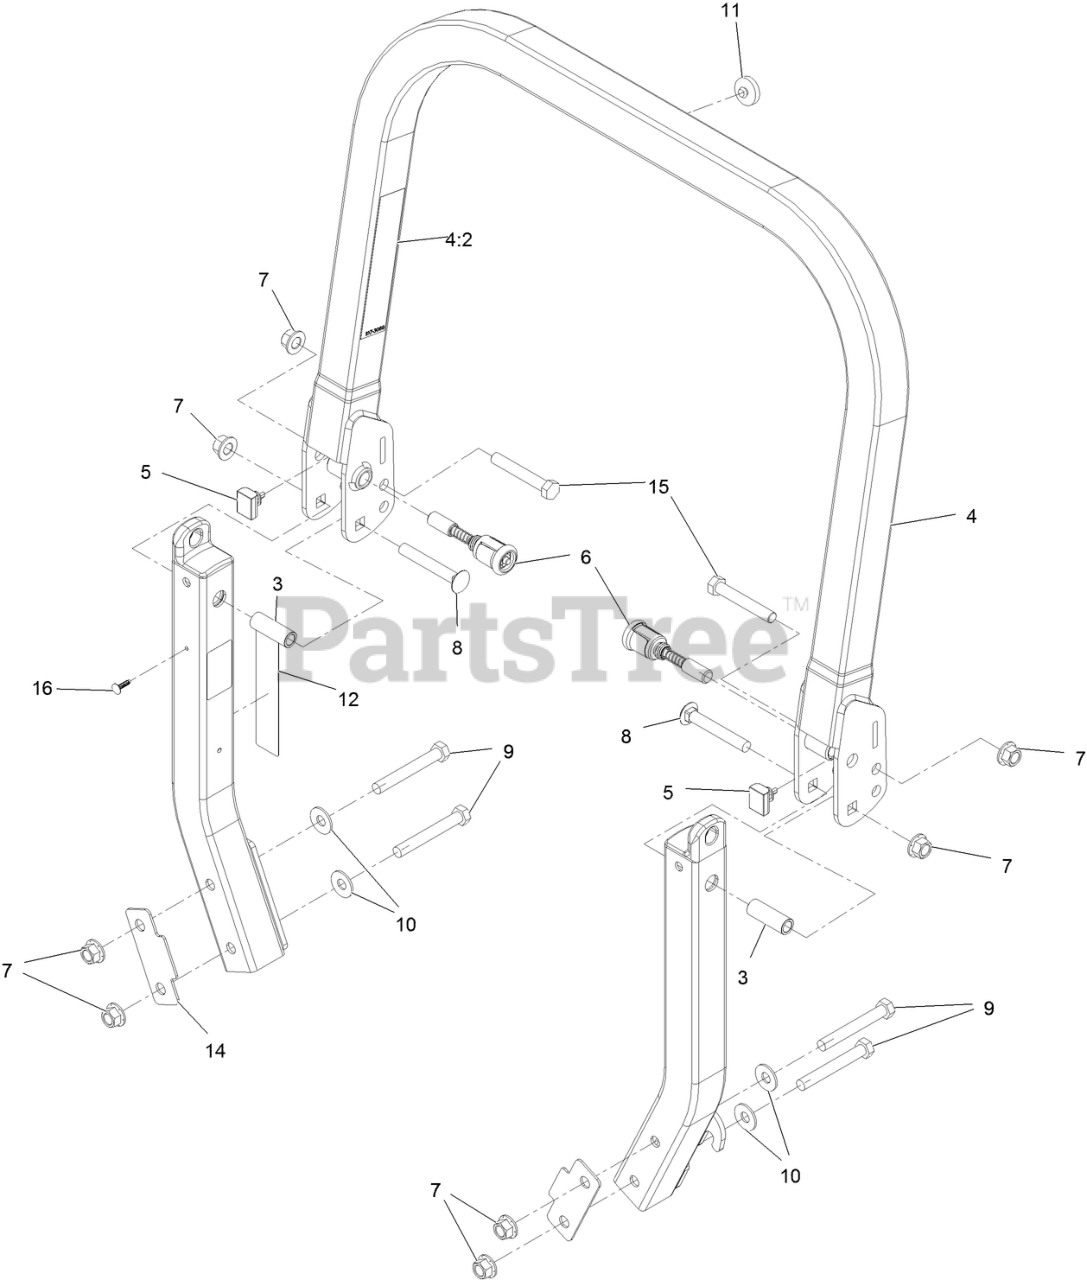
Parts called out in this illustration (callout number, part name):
4	UPPER ROPS ASM
4:2	DECAL-WARNING
5	BUMPER-ROPS
6	PIN-SPRING
7	Nut-Lock 1/2-13
8	SCREW-CARR
9	SCREW-HH
10	WASHER-SPRING
11	BUMPER-PUSH-IN, RUBBER
12	DECAL-CAUTION, FUEL VENT
14	SPACER
15	SCREW-HH
16	PLUG-PLASTIC
